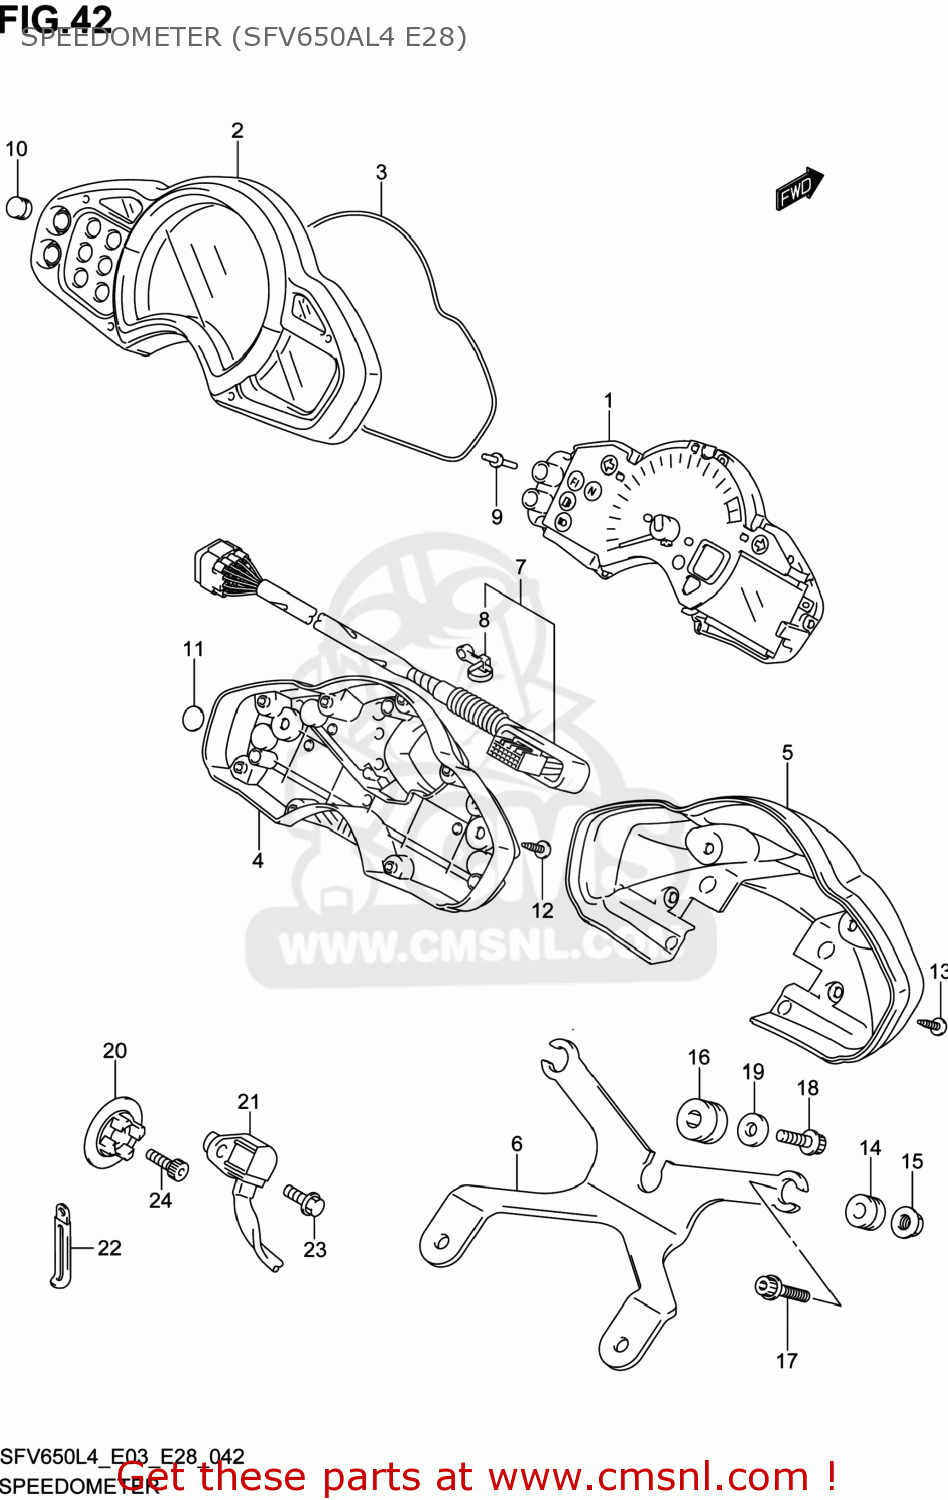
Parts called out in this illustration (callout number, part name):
1	SPEEDOMETER
2	CASE ASSY
3	PACKING RUBBER (NAS)
4	CASE
5	CASE,LWR
6	HOLDER CASE
7	WIRE,ASSY
8	CLAMP,LEAD WIRE
9	KNOB,SPEEDOMETER
10	COVER,SPEEDOMETER
11	SEAL
12	SCREW(3X12)
13	SCREW(4X14)
14	CUSHION,METER
15	NUT
16	CUSHION
17	BOLT
18	SCREW,SPEEDOMETER
19	WASHER
20	ROTOR,SPEED
21	SENSOR,SPEED
22	CLAMP(L:45)
23	BOLT
24	BOLT
